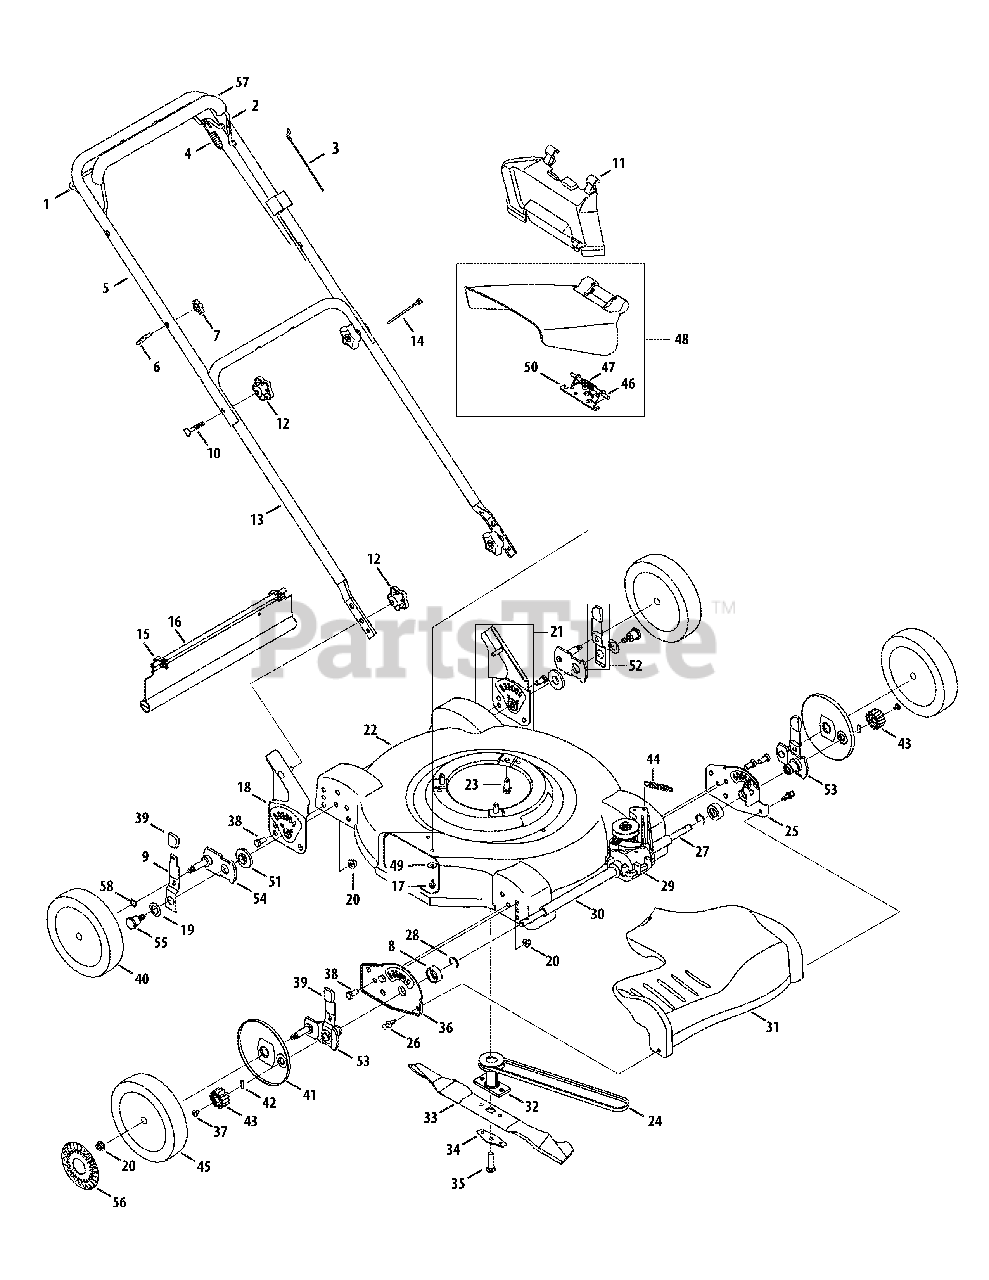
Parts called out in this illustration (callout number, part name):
1	Drive Control
2	Blade Control
3	Control Cable - 37.75"
4	Drive Control Cable
5	Upper Handle
6	Eye Bolt
7	Wing Nut, 1/4-20
8	Bearing Support Spacer
9	Spring Lever
10	Carriage Bolt, 5/16-18 x 2.0
11	Mulching Baffle
12	Star Knob
14	Cable Tie
15	Hinge Clip
16	Trail Shield
17	Hex Screw, 1/4-20 x.500
18	Handle Bracket Assy - RH
19	Bell Washer, .760 x 1.25 x.041
20	Lock Nut, 3/8-16
21	Handle Bracket Assembly - LH
22	22" Deck Assembly
23	Hex Washer Scr., 3/8-16 x 1.0
24	V-Belt, 3L x 32.90
25	Forward Height Adj. Plate - LH
26	Rivet
27	Sleeve Spacer, .550 ID x 2.22
28	Retainer Ring
29	Transmission Assy. Comp.
30	Sleeve Spacer, .550 ID x 8.51
31	Transmission Cover
32	Blade Adapter
33	22" Mulching Blade
34	Blade Bell Support
35	Hex Cap Screw, 3/8-24 x 1.5
36	Forward Hght. Adj. Plate - RH
37	Screw, 1/4-20 x .390
38	Hex Cap Screw, 3/8-16 x.75
39	Adjustment Knob
40	Rear Wheel, 8 x 1.8, Bar
41	Wheel Dust Cover
43	Spur Gear 14T - RH
43	Spur Gear 14T - LH
44	Ext. Spring, .47 OD x 2.50
45	Front Wheel, 8 x 1.8, Bar
46	Hinge Pin
47	Torsion Spring
48	Side Discharge Assembly
49	Bell Washer, .265 ID x.75 OD
50	Deflector Chute Adapter
51	Height Adjustment Bearing
52	Rear Hgt. Adj. Lever Assembly
53	Front Lever Assembly - RH
53	Front Lever Assembly - LH
54	Rear Pivot Arm Assembly
55	Shoulder Screw, 3/8-16
56	Hub Cap
57	Deluxe Bail Cover
58	Washer, Wave, .510 x .750 x .017
